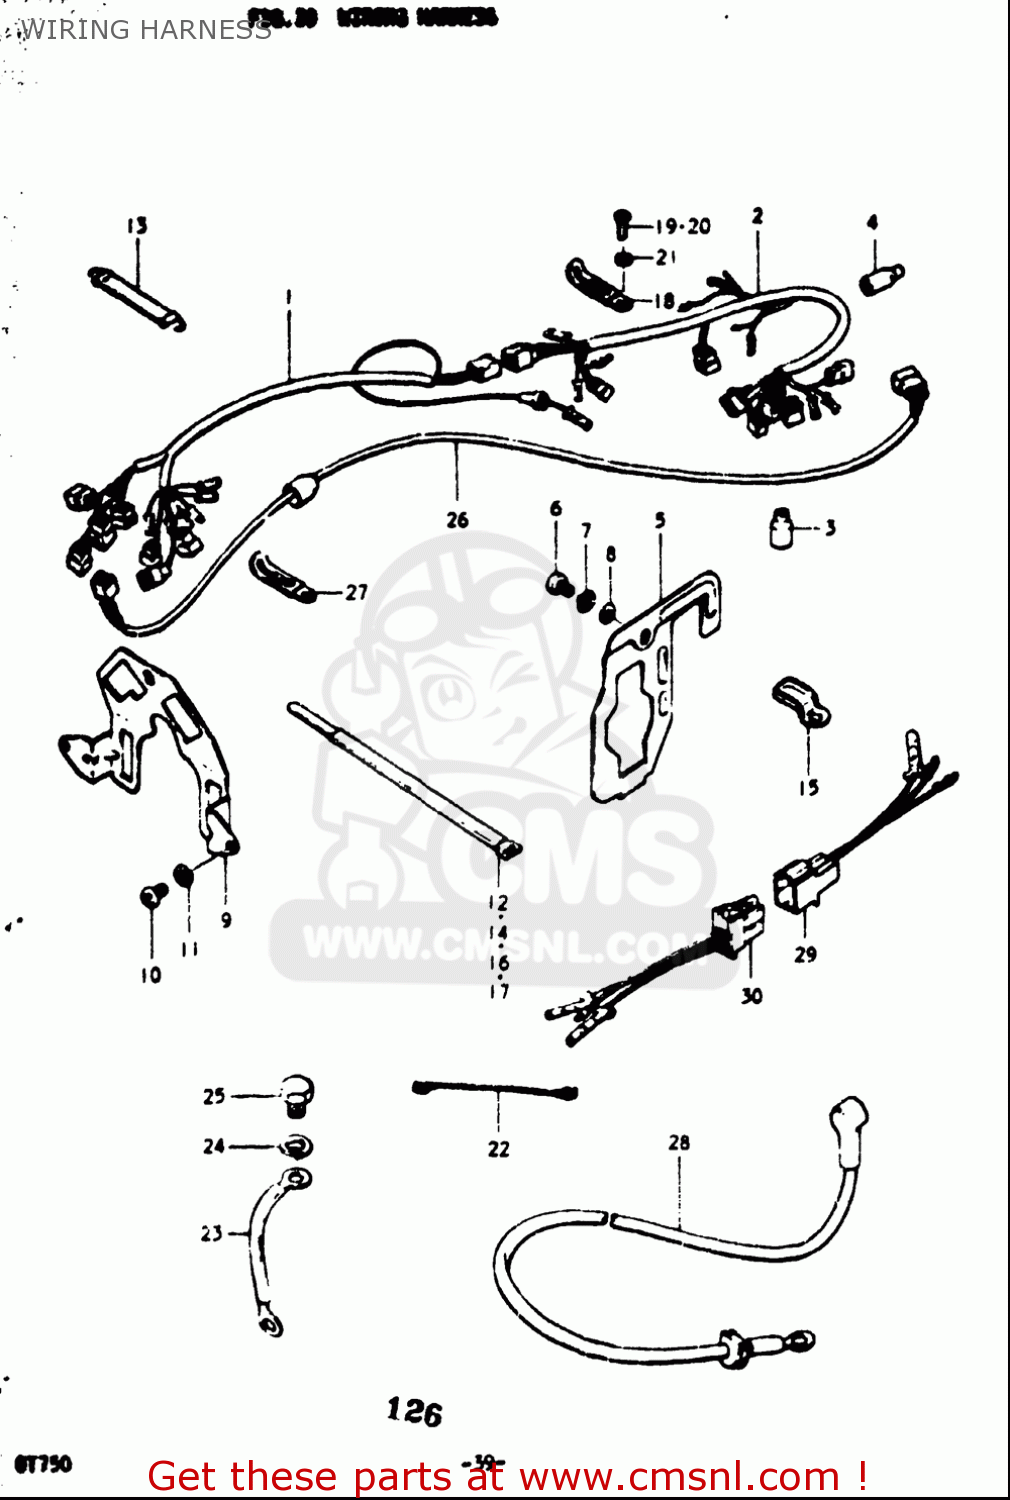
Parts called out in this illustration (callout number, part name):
2	HARNESS,WIRING NO.2
4	BOOT,WIRING HARNESS
6	SCREW
7	WASHER,LOCK
8	WASHER
10	SCREW
11	WASHER,LOCK
12	CLAMP
14	CLAMP
15	CLAMP
16	CLAMP
17	CLAMP
18	CLAMP(L:65)
19	SCREW
20	SCREW
21	WASHER,LOCK
22	LEAD WIRE,EARTH
24	WASHER,LOCK
25	BOLT
27	CLAMP(L:120 T:1.0)
